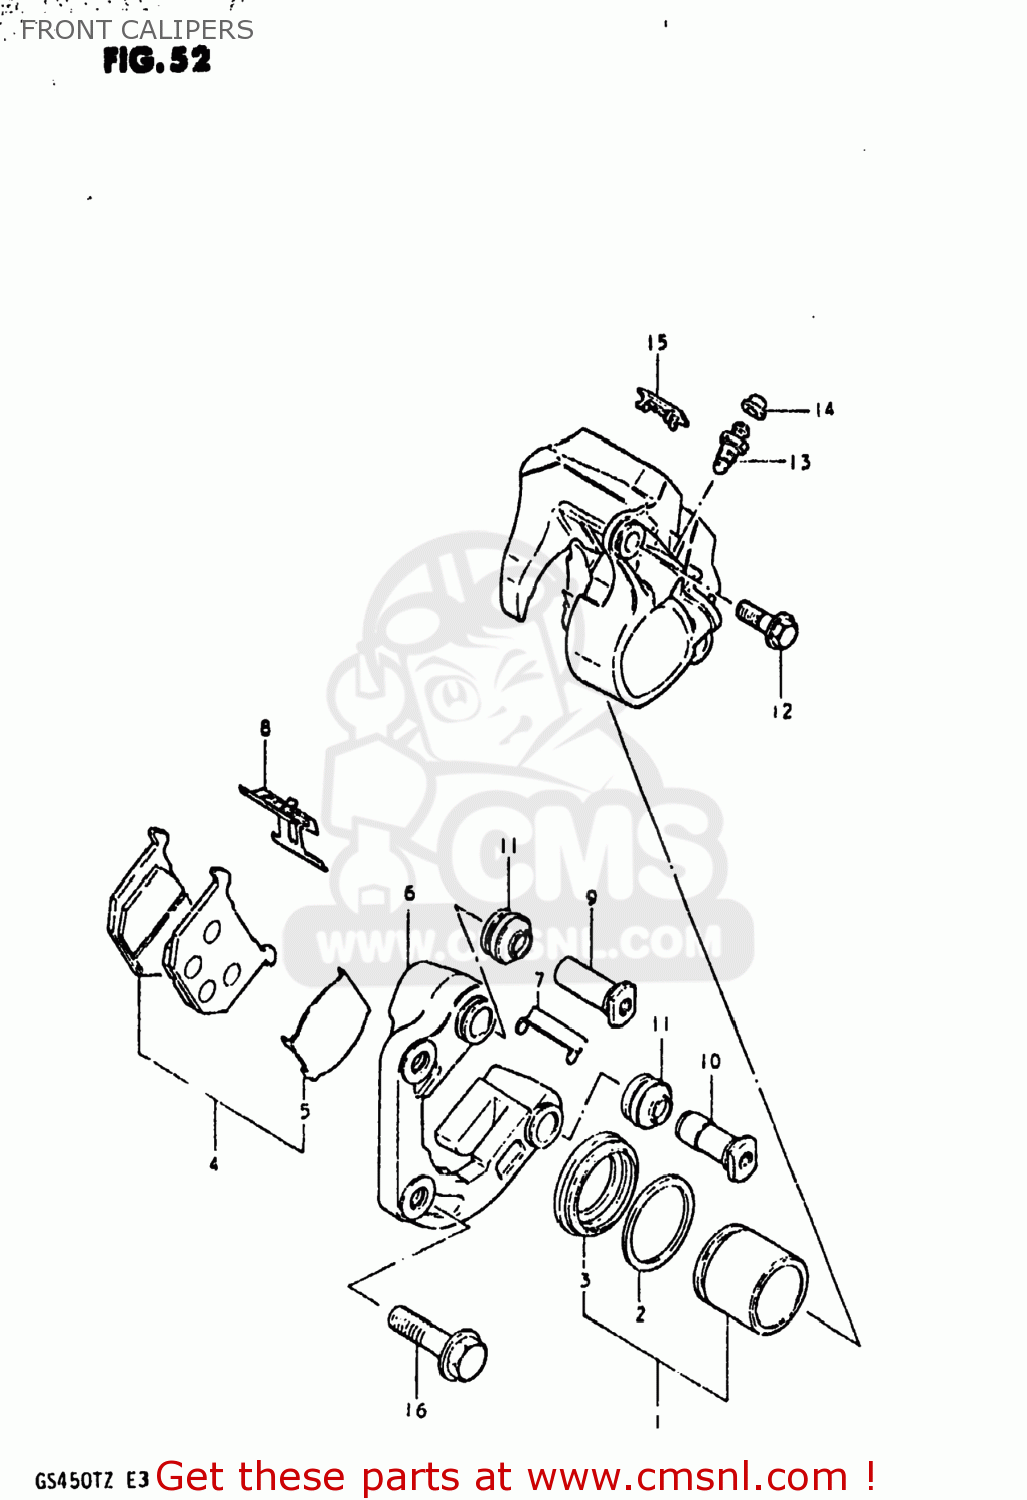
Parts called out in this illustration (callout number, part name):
0	CALIPER ASSEMBLY,FRONT,LEFT
1	PISTON SET
2	SEAL,FR CALIPE
3	BOOT,PISTON
4	PAD SET (MCA)
5	SHIM,PAD
6	CARRIER,CALIPER,LEFT
7	GUIDE,PAD
8	SPRING,PAD
9	AXLE NO.1
10	AXLE NO.2
11	BOOT,AXLE
12	BOLT,CALIPER HOUSING
13	BLEEDER
14	CAP,BREATHER
15	COVER,INDICATOR
16	BOLT(10X37)
